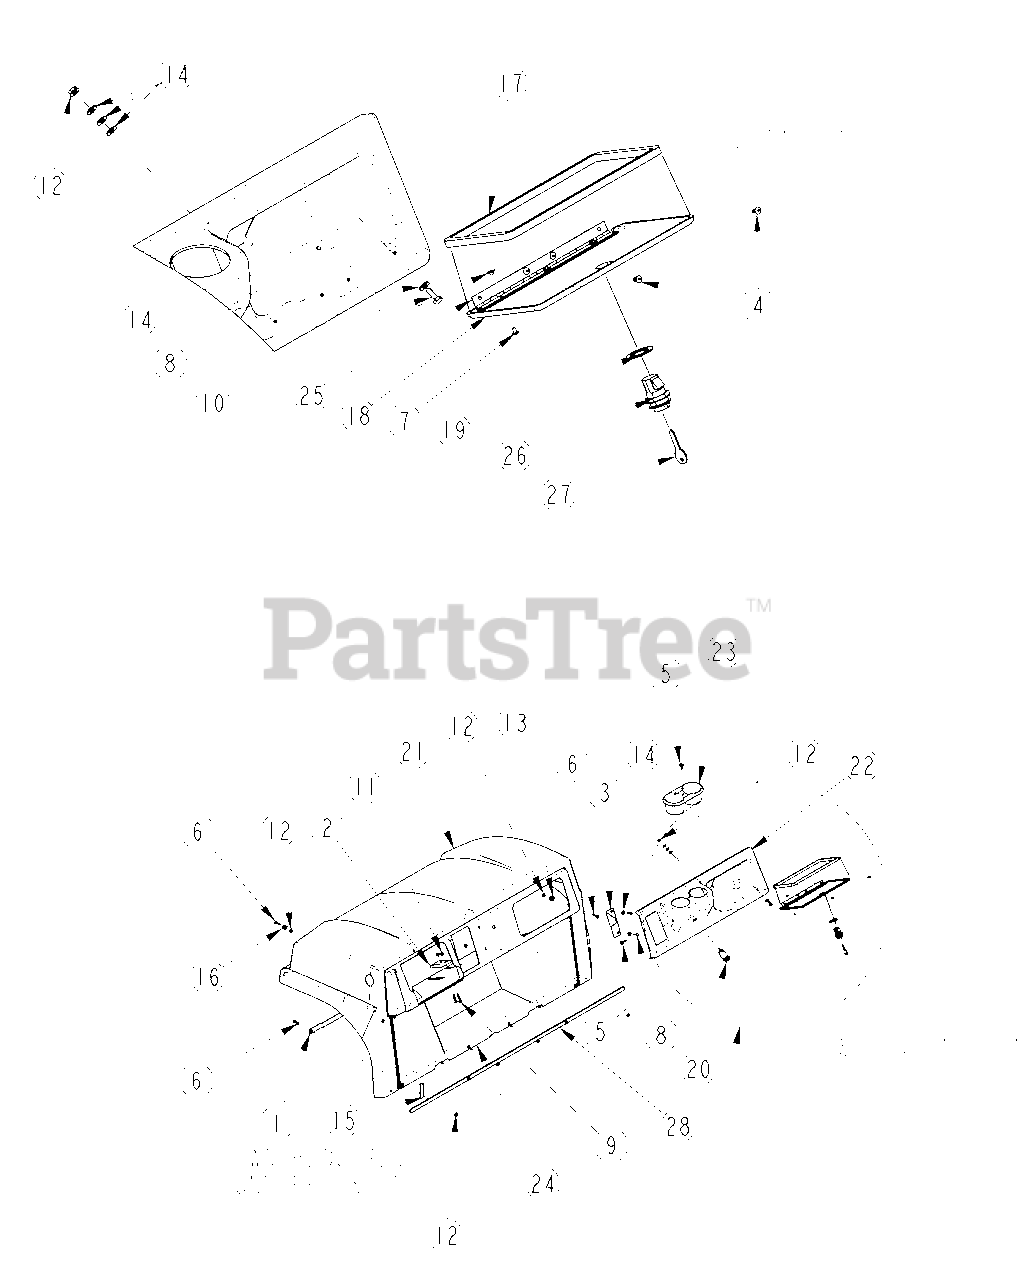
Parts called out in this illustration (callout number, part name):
1	BACKING PLATE FOR TRUCK BODY
2	BODY MOUNT SPACER .375 THICK As Required
3	DASH MOUNT PLATE
4	RIVET POP 3/16 .126-.250
5	RIVET, 1/4 REMOVEABLE
6	TPHMS Y 1/4-20X1 YELLOW DIE
7	PHMS #8-32 X 1/4, SS BLACK
8	HHCS 1/4-20X3/4 GR5
9	HHCS 5/16-18X1 1/4 GR5
10	NUT, BINDER 8-32 X 1/8
11	NUT HEX FLG TOP LK 5/16-18 YLW
12	NUT HEX FLNG T-LOCK 1/4-20 PLT
13	WASHER FLAT 3/8 USS PLT
14	WASHER FLAT 1/4 HARD ASTMF436
15	TRIM, 1/8 RUBBER EDGE (PER FT)
16	RUBBER GROMMET .75DX.31IDX.37T
17	SEAL, GLOVE BOX DOOR
18	DOOR, TRUCK GLOVE BOX
19	WASHER, 1 1/2 X 1 X .08 THICK
20	POWER PLUG OUTLET 12V
21	SERV - ST 4X2 BODY-RED W/DECAL
22	10 SERIES DASH W/DECALS
23	CUP HOLDER INSERT
24	4210ST FOOTWELL W/ DECALS
25	HINGE, 1.25 X 10 CONTINOUS
26	LATCH, LOCKABLE TWIST
27	KEY GLOVE BOX DOOR- TWIST LOCK
28	FOAM RUBBER 3/16X3/4 THK W/PSA 52.5" Lg.
